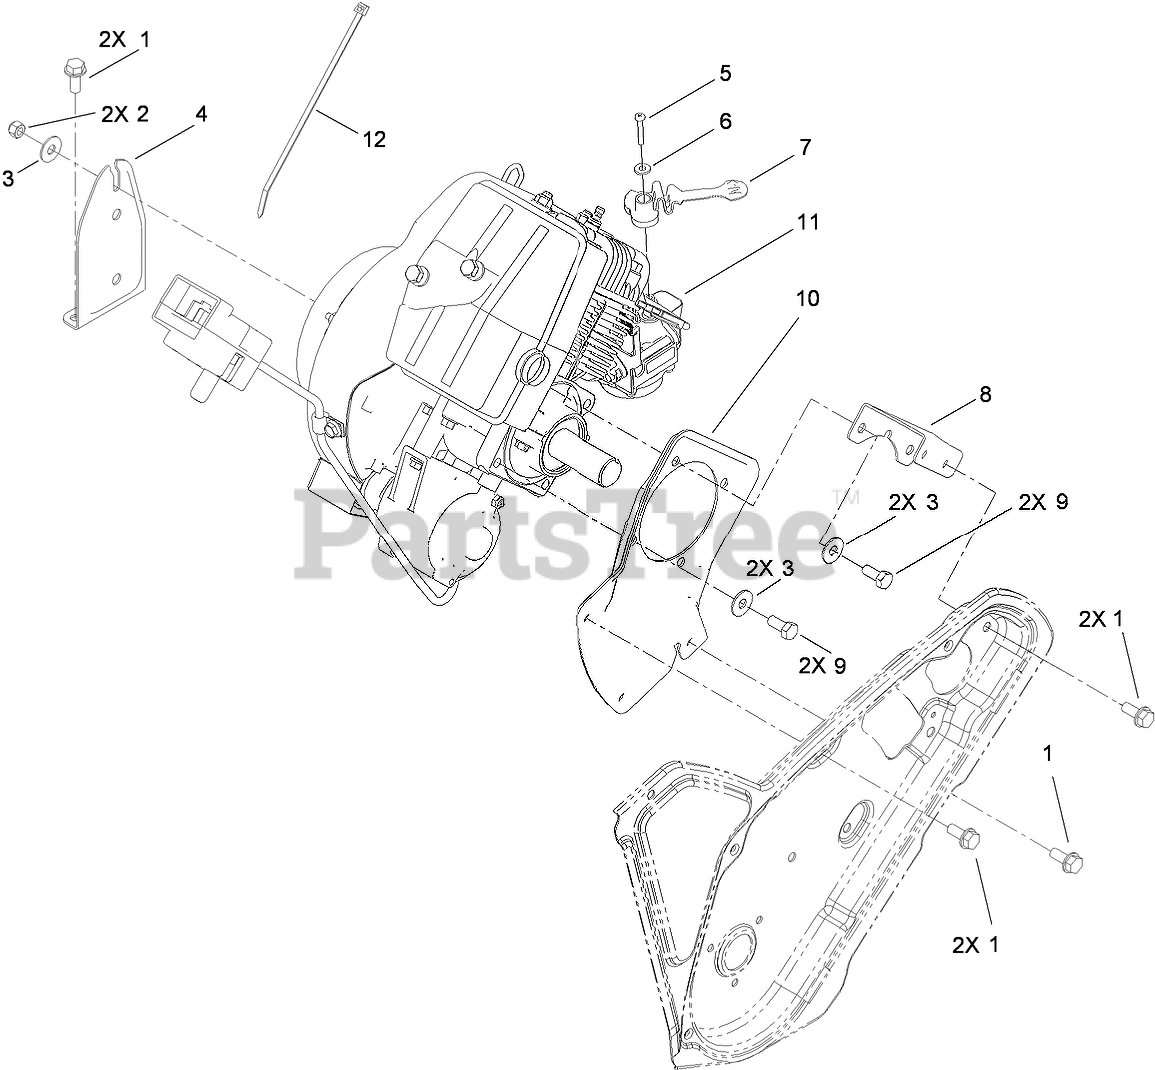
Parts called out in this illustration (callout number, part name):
1	SCREW-HWHTF
2	NUT-LOCK, NI
3	WASHER-BELLEVILLE
4	BRACKET-RECOIL
5	SCREW-PPH, PLASTITE
6	WASHER-FLAT
7	LEVER-CHOKE
8	SUPPORT-ENGINE, SIDE
9	SCREW-HH
10	PLATE-ENGINE, PTO
12	TIE-CABLE
